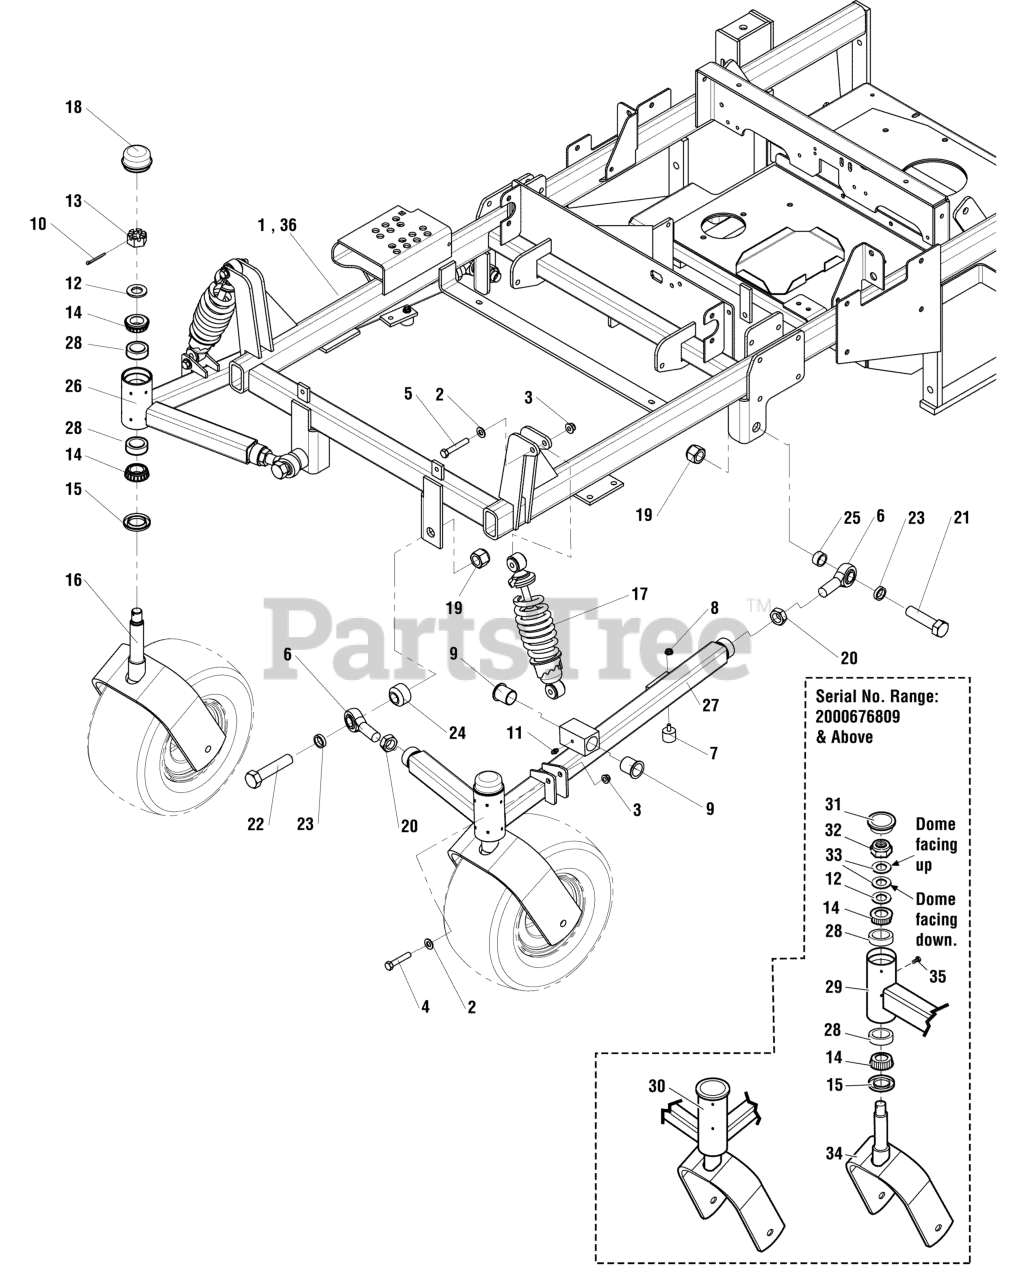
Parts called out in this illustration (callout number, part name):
1	WELD, MAIN FRAME, IS3000Z
2	WASHER 3/8" GD. 9 FLAT
3	NUT, 3/8-16 HEX NYLOCK FLANGE
4	BOLT, 3/8-16 X 2, GD5, CZ
5	BOLT, 3/8-16 X 2-1/4" GD5 CZ
6	BALL JOINT, 3/4-16 MALE
7	BUMPER, RUBBER 1/4-20
8	NUT, 1/4-20 HEX SERR. FLANGE
9	FLANGE BUSHING
10	PIN, COTTER, 1/8 X 1-1/4
11	GREASE FITTING, 1/4-28 STR
12	WASHER, 3/4 SAE
13	NUT, 3/4-16 HEX SLOTTED
14	BEARING, TAPPERD ROLLER, 1"
15	SEAL, GREASE
16	WELD, CASTER YOKE
17	COIL - OVER SHOCK ASSEMBLY
18	CAP, DUST
19	NUT, 3/4-16 HEX NYLON LOCK
20	NUT, HEX JAM, 3/4-16
21	BOLT, 3/4-16 X 3" GD 5
22	3/4-16 X 3.5" HHCS YZP GR 5
23	SPACER, .76 X 1.00 X .25
24	SPACER, .75 X 1.50 X 1.00
25	SPACER, .76 X 1.00 X .50
26	ASSM, A-ARM, RH
27	ASSM, A-ARM, LH
28	BEARING CUP
29	WELD, A-ARM - RH - RED
30	WELD, A-ARM - LH - RED
31	CAP, GREASE, LOW PROFILE
32	NUT, 3/4-16, HEX JAM NYLON LOCK
33	BELLEVILLE WASHER, 1.500 X .755
34	WELD, CASTER YOKE - RED
35	BOLT, 1/4-28 X 1/2, GD5 YZ
36	WELD, MAIN FRAME, IS3100Z
